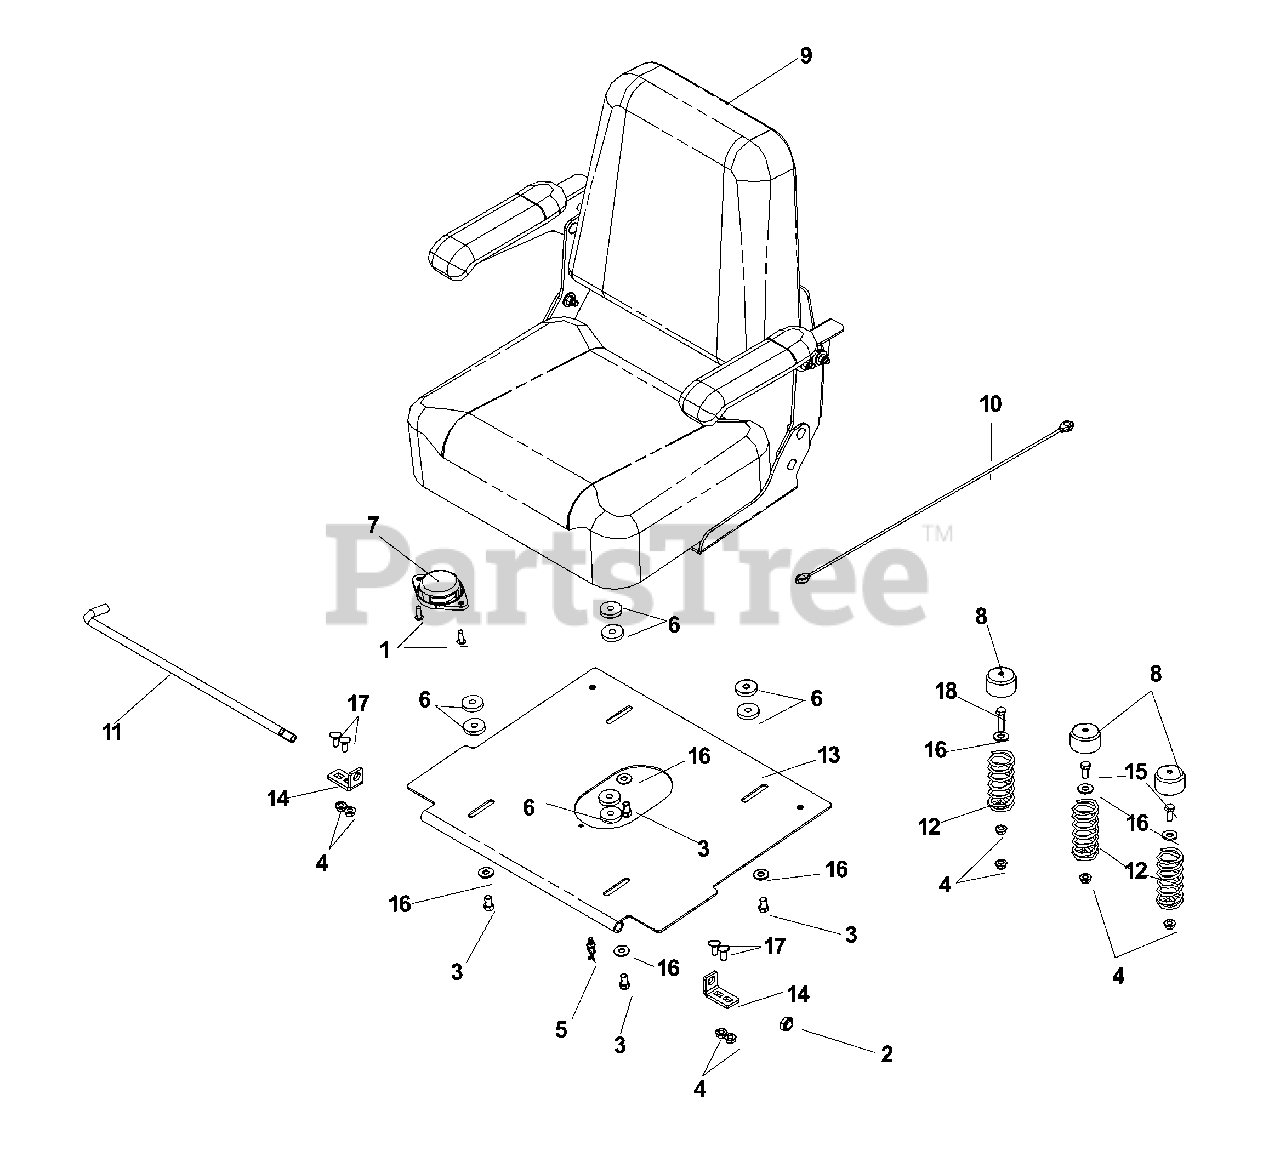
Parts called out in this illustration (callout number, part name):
1	SCR 1/4-20X3/4 SLTD RDHD GR2ZD
2	NUT, 1/2-13 THIN PROF NYL
3	CAPSCREW 5/16 X 1/1/2 HEX HEAD
4	5/16-18 FLANGED L-NUT
5	LINK RETAINER
6	WASHER NYLON
7	SEAT SWITCH MILSCO
8	SPRING CAP
9	SEAT CORDURA
10	LANYARD SEAT
11	SEAT PIN
12	SEAT SPRING
13	SEAT PLATE DK-BLUE
14	SEAT PIVOT DK-BLUE
15	HCS 5/16C X 3/4
16	FLAT WASHER 5/16 SAE
17	BOLT 5/16C X 3/4" CARRIAGE
18	HCS 5/16C X 1 1/4
